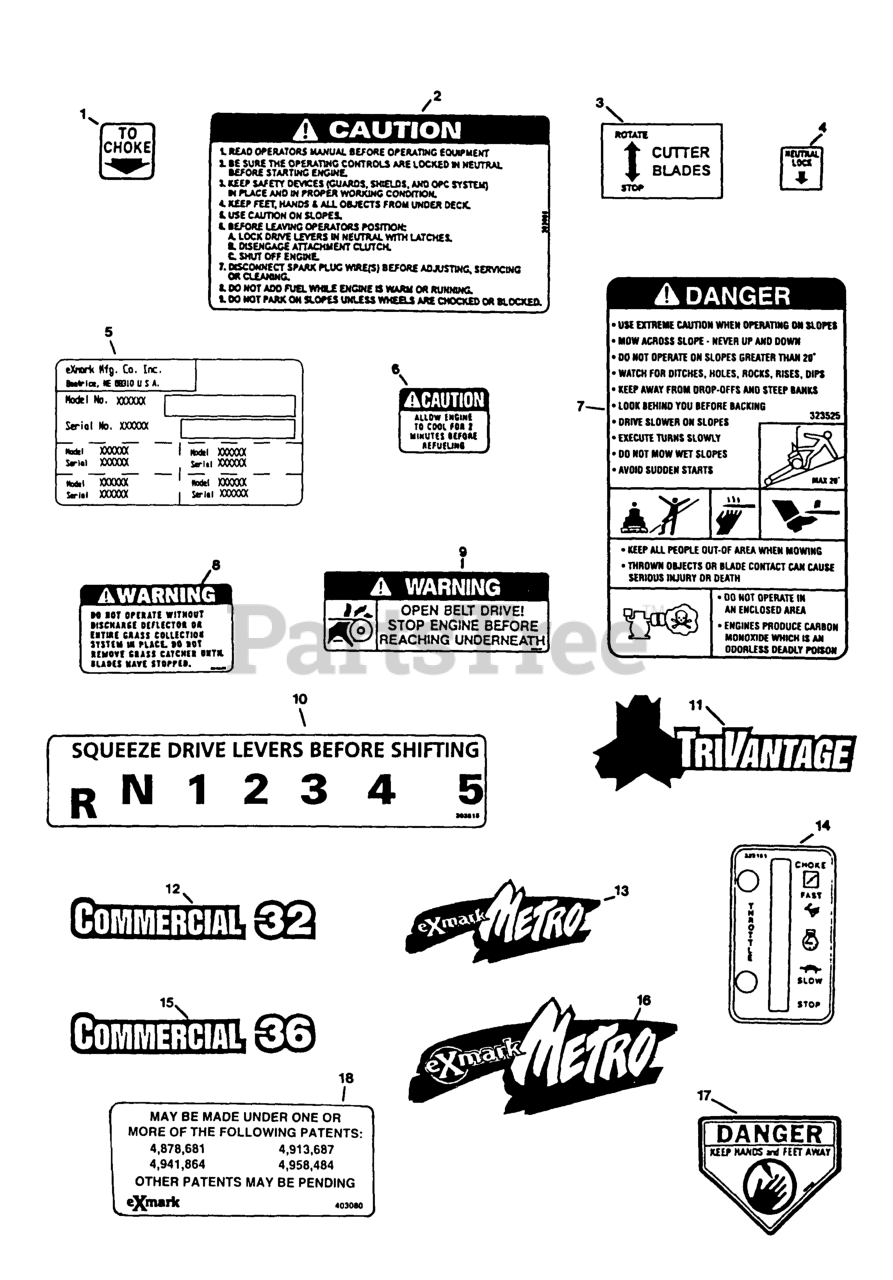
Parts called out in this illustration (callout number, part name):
2	LABEL,INSTRUCTION
3	DECAL,CUTTER BLADE
4	DECAL,NEUTRAL LOCK
8	DECAL-WARNING, DISCHARGE
9	DECAL,BELT DRIVE
10	DECAL,SHIFTER
12	DECAL,COMMERCIAL 32
15	DECAL,COMMERCIAL 36
17	DECAL-DANGER
